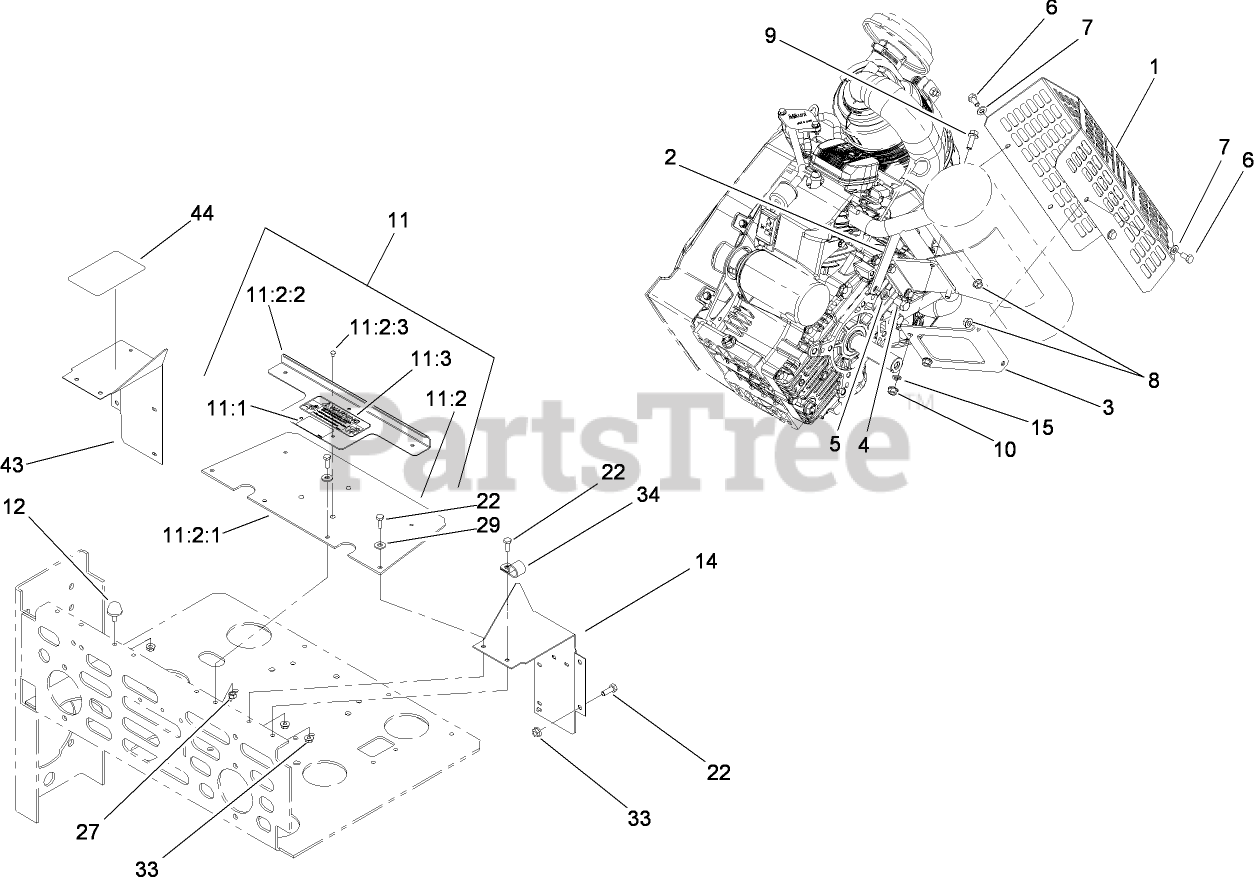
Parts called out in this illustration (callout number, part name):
1	GUARD-MUFFLER
2	BRACKET-MOUNT, MUFFLER
3	BRACKET-SUPPORT, MUFFLER
4	SCREW-HH
5	WASHER-LOCK
6	SCREW-HH
7	WASHER-PLAIN
8	NUT-HF
9	SCREW-HHF
10	NUT-HF
11	SHIELD ASM
11:1	DECAL-IMPORTANT
11:2	Drive Cover ASM
11:2:1	SHIELD-ENGINE
11:2:2	PLATE-COVER, DRIVE
11:2:3	RIVET-POP
11:3	DECAL-DEVICES, ROTATING
12	BUMPER-RUBBER
14	BAFFLE-ENGINE SHIELD, LH
15	WASHER-LOCK, SPRING
22	SCREW-HH
27	NUT-LOCK, NI
29	WASHER-FLAT
33	NUT-HF
34	CLIP-LOOM
43	SHIELD-RH
44	DECAL-ROUTING, BELT
